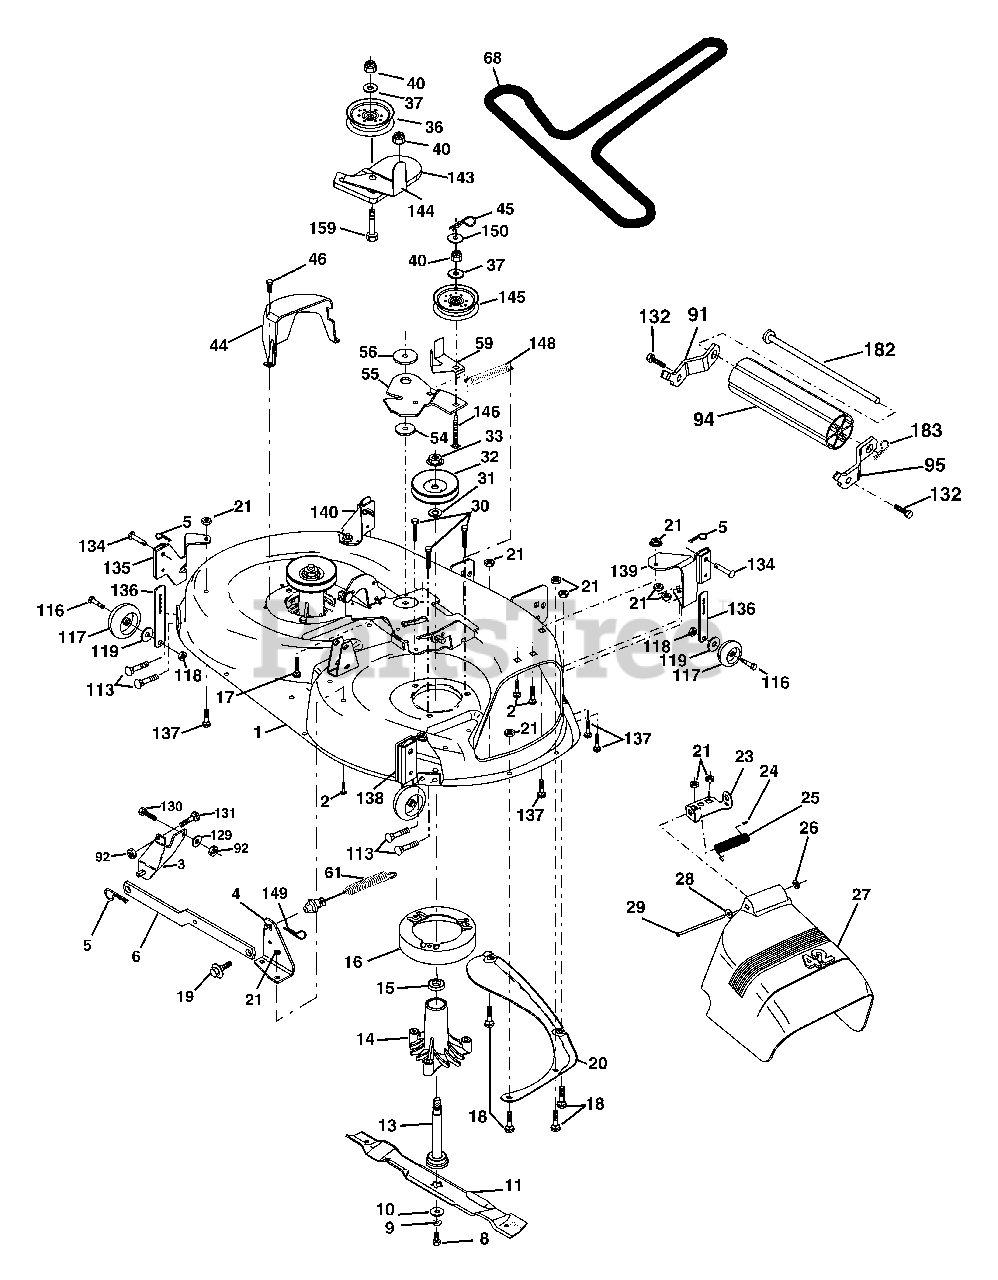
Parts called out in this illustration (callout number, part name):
1	Mower Deck Assembly, 42"
2	Bolt
3	Bracket Asm Fr. Sway Bar 3/42
4	Bracket Asm Deck 42" Sway Bar
5	Retainer Spring
6	Bar Sway Deck
8	Bolt 3/8-24 x 1.25 Gr. 8 patched
9	Washer, Lock
10	Washer, Hardened
11	Blade Mower 42" Hi-Lift (for bagging and discharging)
11	Blade, Mulching 42" Std (for mulching mowers only)
11	Blade Mulching 42" Premium (For better wear when mulching)
13	Shaft Assembly, Mandrel, Vented
14	Housing, Mandrel, Vented
15	Bearing, Ball, Mandrel
16	Stripper, Mandrel Deck
18	Bolt, Carriage 5/16-18 x 5/8
19	Bolt, Shoulder
20	Baffle, Vortex
21	Nut
23	Bracket, Deflector Mower 42"
24	Cap, Sleeve 80 x 112 Blk Mower
25	Spring, Torsion, Deflector 2 52
26	Nut, Push Phos & Oil
27	Shield, Deflector 42" Blk
28	Washer
29	Rod, Hinge 42" 6 75 W/G
30	Screw Thdrol
31	Washer, Spacer Mower Vented
32	Pulley, Mandrel
33	Nut, Toplock
34	Bolt Carr SH 3/8-16 x 1-1/2 Gr.5
36	Pulley, Idler, Flat
40	Nut Lock 3/8-16
44	Guard, Mandrel, LH
45	Retainer
46	Screw, Thdrol 1/4-20 x 5/8 T
54	Washer, Hardened
55	Arm, Idler
56	Spacer, Retainer
59	Guard TUV Idler
61	Spring Ext Elect. Clutch
68	V-Belt, 42" Mower
91	Bracket Roller Nose RH
92	Nut Lock Hex w/Ins 3/8-16 unc
94	Roller Nose
95	Bracket Roller Nose RH
113	Screw 5/16-18
116	Bolt, Shoulder
117	Wheel, Gauge
118	Nut Centerlock 3/8-16
119	Washer 3/8 x 7/8 x 14 Ga.
129	Washer 13/32 x 13/16 x 12 Ga.
130	Bolt Fin HEx 3/8-16 unc x 1 Gr. 5
131	Bolt RDHD SQNK 3/8-16 unc x 1
132	Screw Hexwsh Thdrol
134	Pin Head Rivet
135	Bracket Asm. Wheel Ga. Rear LH
136	Bar Adjusting Wheel Ga.
138	Bracket Asm. Wheel Ga. Rear RH
139	Bracket Asm. Wheel Ga. Front RH
140	Bracket Asm. Wheel Ga. Front LH
143	Bracket Arm Idler 42"
144	Keeper Belt 42" Clutch Cable
145	Pulley Idler Flat
146	Bolt Carriage Idler
148	Spring Return Idler
149	Retainer Spring Yellow
150	Washer 9/32 x 3/4 x 10 Ga.
159	Bolt Rdhd Sqn 3/8-16 unc x 1-3/4
182	Rod Roller Nose
183	Retainer Spring
184	Washer 13/32 x 7/8 x 10 Ga.
